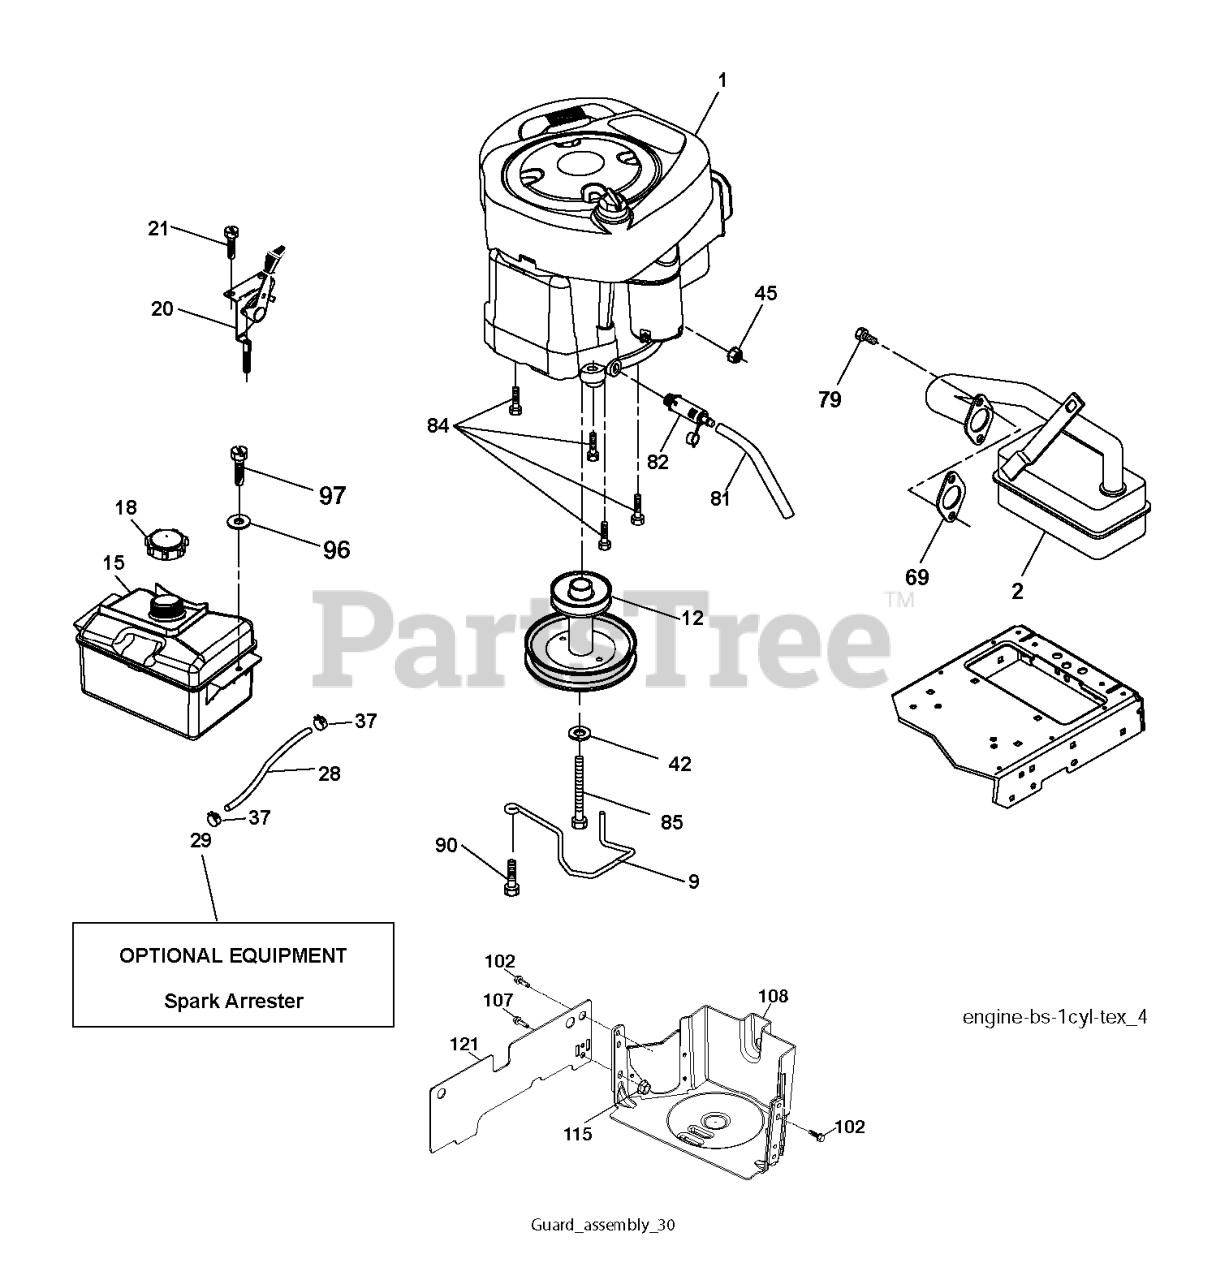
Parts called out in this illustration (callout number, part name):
2	MUFFLER.B&S.MODEL.21.11HP.OHV
9	KEEPER.BELT.ENGINE.3.25 (3 2)
12	PULLEY.ENG.CL.MECH.SLVR.LT/YT
15	RP TANK FUEL FRT 1.5 GAL
18	FUEL CAP
20	CONTROL.TH/CK.C.
21	SCREW.#10 X 0.750.BOS
28	LINE.FUEL.20
29	KIT.SPARK ARRESTOR 794945 B&S
37	HOSE CLAMP
42	LOCKWASHER
45	NUT
69	REPL BY 532 27 22-93
79	SCREW.SOCKET HD.5/16-1
81	TUBE, DRAIN OIL ASM.
82	PLUG DRAIN OIL EASY
84	SCREW.3/8-16
85	BOLT HEX 7/16-20X4-1/4"
90	SCREW 3/8-16X1
97	SCREW HEXWSHR 1/4-20X3/4
102	SCREW
107	SCREW.1/4-20X5/8
108	COVER PULLEY
115	PALNUT 1/4
121	SHIELD LEFT
